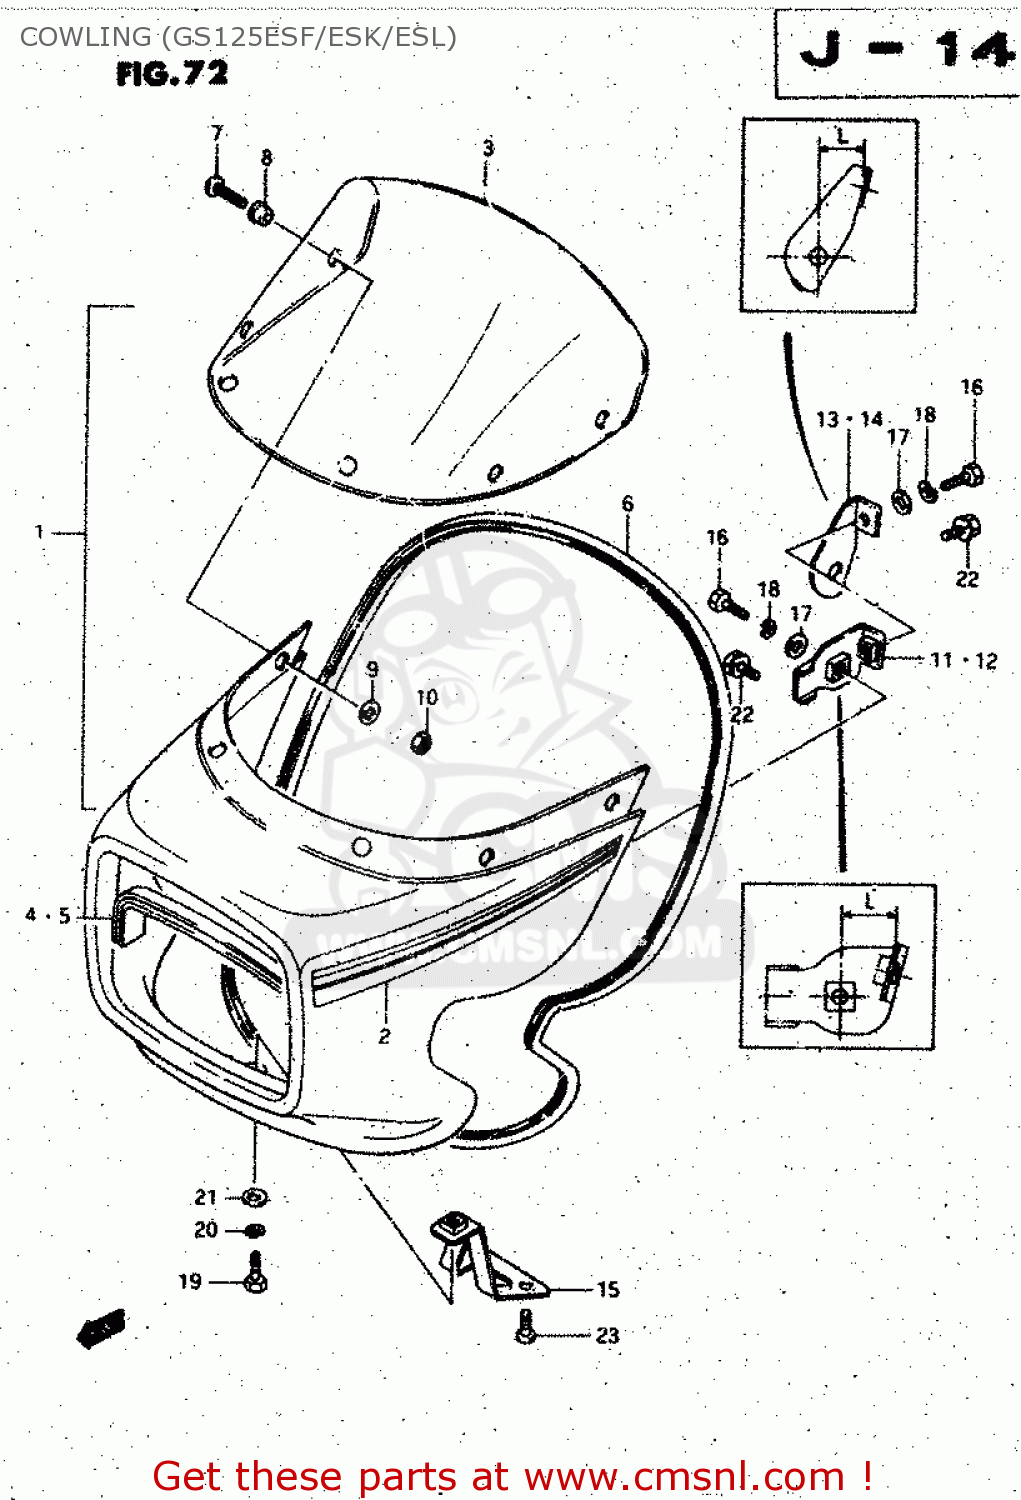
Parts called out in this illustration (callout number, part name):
1	COWLING ASSY (RED)
2	TAPE SET
3	WINDOW,COWLING
4	MOLDING,HEADLAMP GRILL
5	MOLDING,HEADLAMP GRILL
6	MOLD,COWLING
7	SCREW, FRONT & REAR
8	CUSHION
9	WASHER,5MM
10	NUT ,5MM
11	BRACE, RH (L:19)
12	BRACE,COWLING LH
13	BRACKET, FITTING RH (L:19)
14	BRACKET,L
15	BRACKET, LOWER
16	BOLT 6X16
17	WASHER (6.5X18X1.6)
18	WASHER,LOCK
19	BOLT 6X16
20	WASHER,LOCK
21	WASHER (6.5X18X1.6)
22	BOLT ,6X12
23	SCREW
